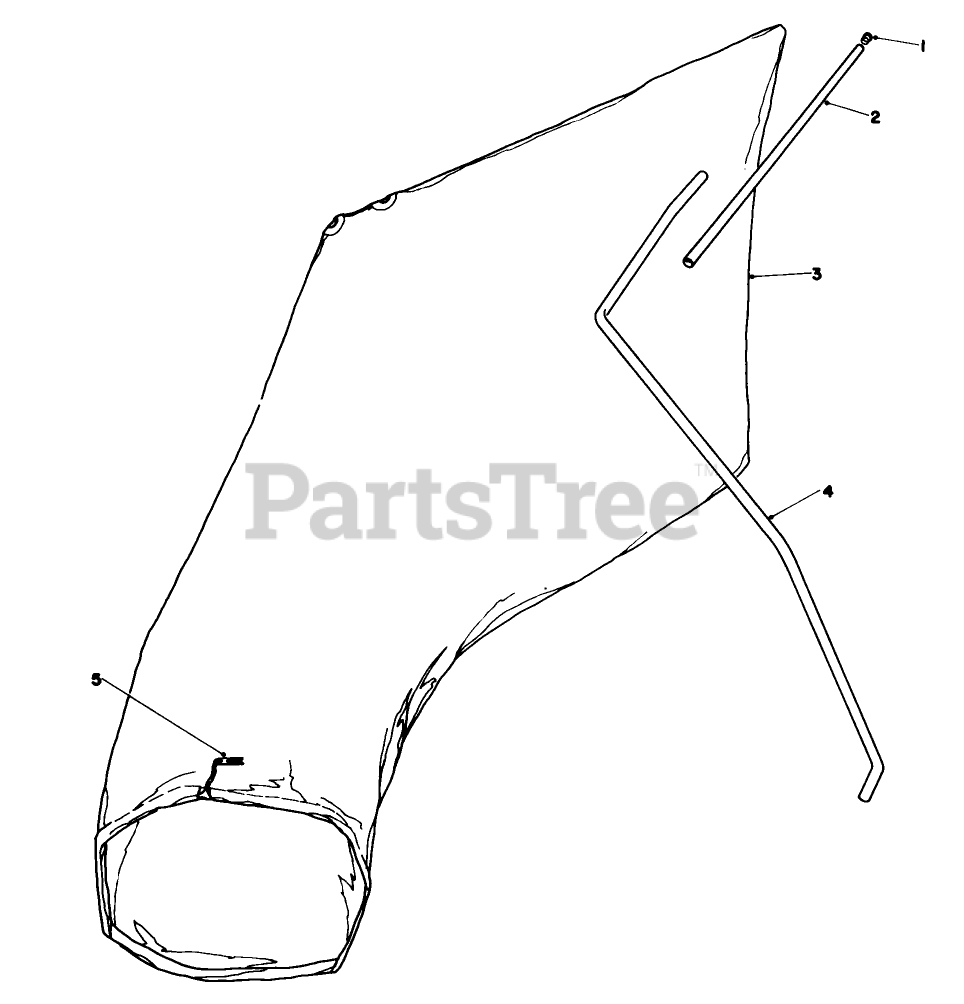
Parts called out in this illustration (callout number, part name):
2	BAG HANGER TUBE
3	Bag (Incl. Ref. #5)
4	4820 Hanger Rod
5	BAG CORD FASTENER
